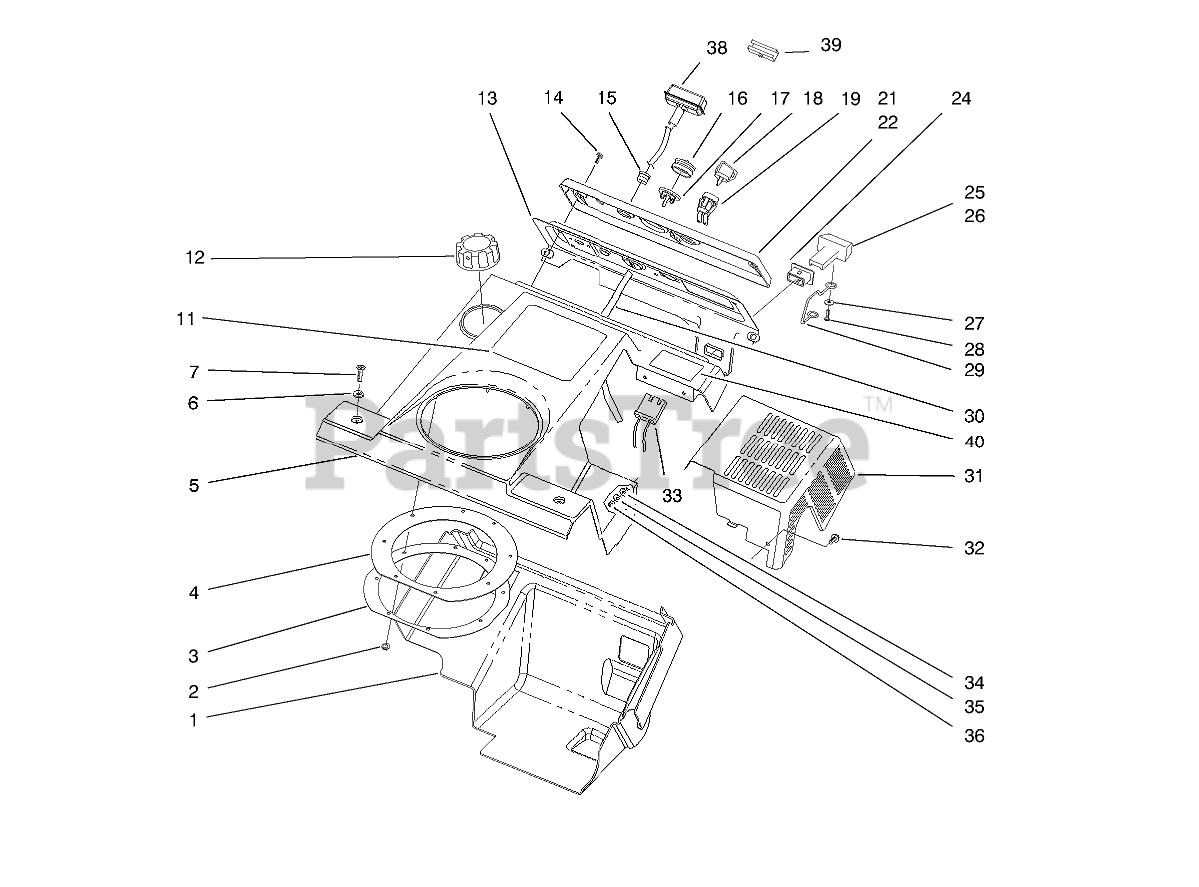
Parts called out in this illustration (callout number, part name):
1	SHROUD - LOWER
2	PALNUT
3	CHUTE SEAL RETAINER RED
4	SEAL-CHUTE
5	SHROUD - UPPER
6	WASHER-FLAT
7	SCREW-PPH
11	DECAL - CCR 2400 GTS
12	CAP-FUEL ASM
13	Wa-Panel
14	SCREW-HWH
15	GUIDE-ROPE, STARTER
16	BULB-PRIMER
17	BODY-PRIMER
18	KEY-IGNITION
19	SWITCH
21	CONTROL NAMEPLATE
22	NAMEPLATE-CONTROL
24	FITTING
25	CHOKE CONTROL
26	CONTROL-CHOKE
27	WASHER-PLAIN
28	SCREW-PPH
29	LINKAGE-CHOKE
30	HOSE-PRIMER
31	Shield-Heat
32	SCREW-SHH
33	CONNECTOR-BODY
34	WASHER
35	WASHER-FLAT
36	NUT-LOCK, NI
38	HANDLE-START
39	CLIP-STARTER
40	DECAL
